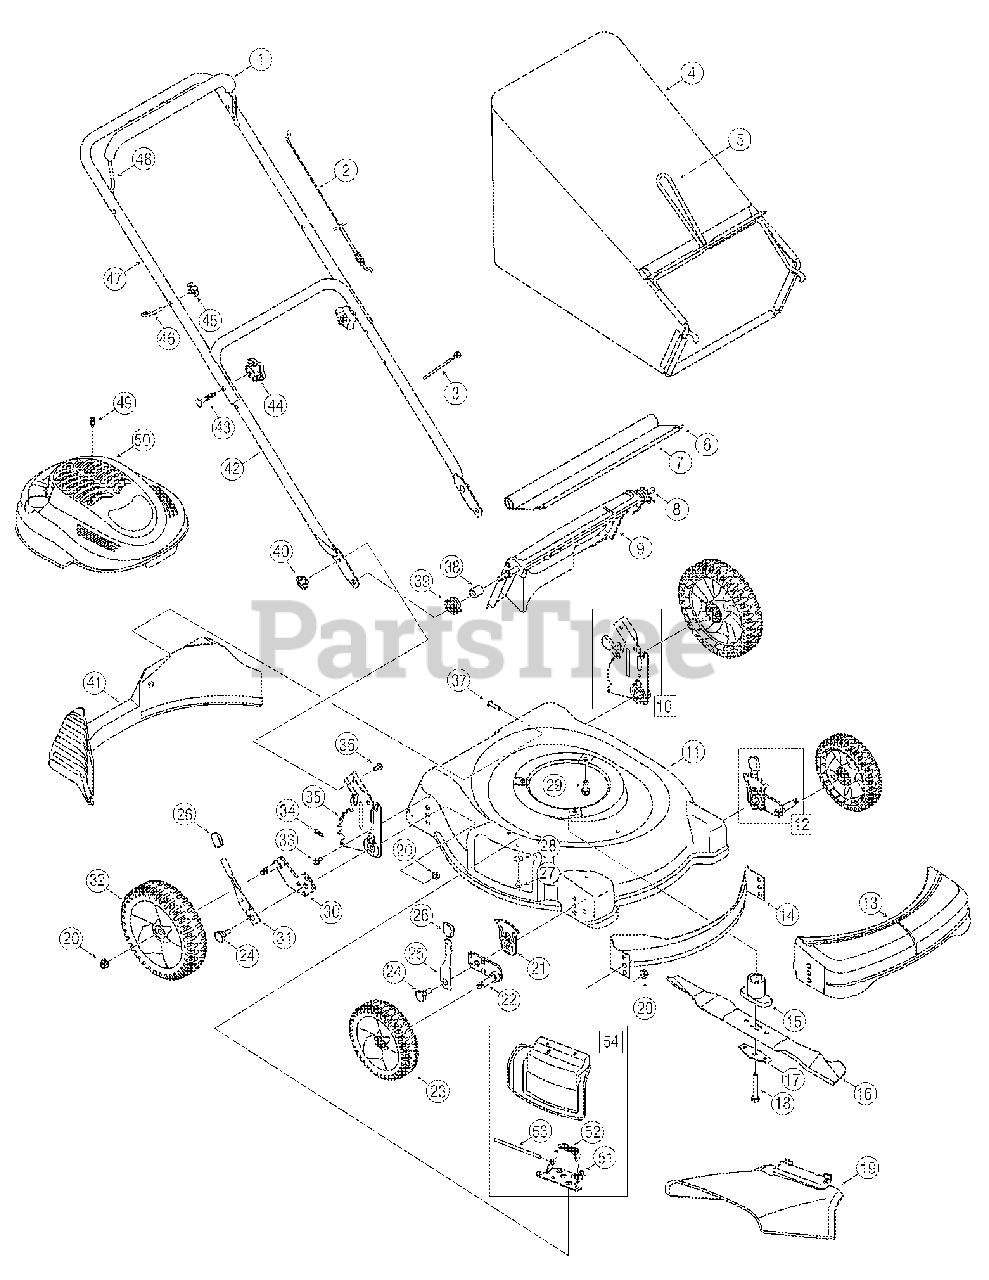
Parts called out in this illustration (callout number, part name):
1	Bail Cover
2	Control Cable 40-inch
2	Control Cable 53-inch
3	Cable Tie
4	Grass Bag Assembly
6	Trailshield Wire
7	Trailshield
8	Pivot Rod
9	Rear Door
10	Height Adj. Bracket Assy - LH
10	Height Adj. Bracket Assy - RH
12	Hgt. Adj. Assy - RH (7-inch Wheel)
13	Front End Cover, 21-inch
14	Front Baffle
15	Blade Adapter
16	21-inch Mulching Blade
17	Bell Blade Support
18	Hex Bolt 3/8-24 x 2.5 long
19	Side Discharge Chute
20	Flange Lock Nut 3/8-16
21	Height Adjustment Plate
22	Pivot Arm Assy - RH
22	Pivot Arm Assy - LH
23	Wheel 7 x 1.8 Pin Bar
24	Shoulder Screw .5 x .434
25	Spring Lever
26	Height Adjust Knob
27	TT Screw 1.4-20 x .50
28	Bell Washer .265 x .75 x .062
29	TT Sems Screw 3.8-16 x 1.00
30	Pivot Arm Assy - RH
30	Pivot Arm Assy - LH
31	Spring Lever
32	Wheel 8 x 1.8 Pin Bar
33	TT Screw 1/4-20 x .625
34	Int. Cotter Pin .072 dia. x 1
35	Rear Handle Bracket - RH
35	Rear Handle Bracket - LH
36	Carriage Screw 1/4-20 x .75
37	Screw HL 1/4-15 x 1.00
38	Spacer
39	Torsion Spring - RH
39	Torsion Spring - LH
40	Wing Nut
41	Rear Baffle
43	Carriage Bolt 5/16-18 x 2.0
44	Star Knob
45	Handle Knob
46	Eye Bolt
49	Shoulder Screw
50	Engine Shroud
51	Chute Deflector Adapter
52	Torsion Spring .290 ID x 1.68
53	Hinge Pin
54	Mulch Plug Assembly
